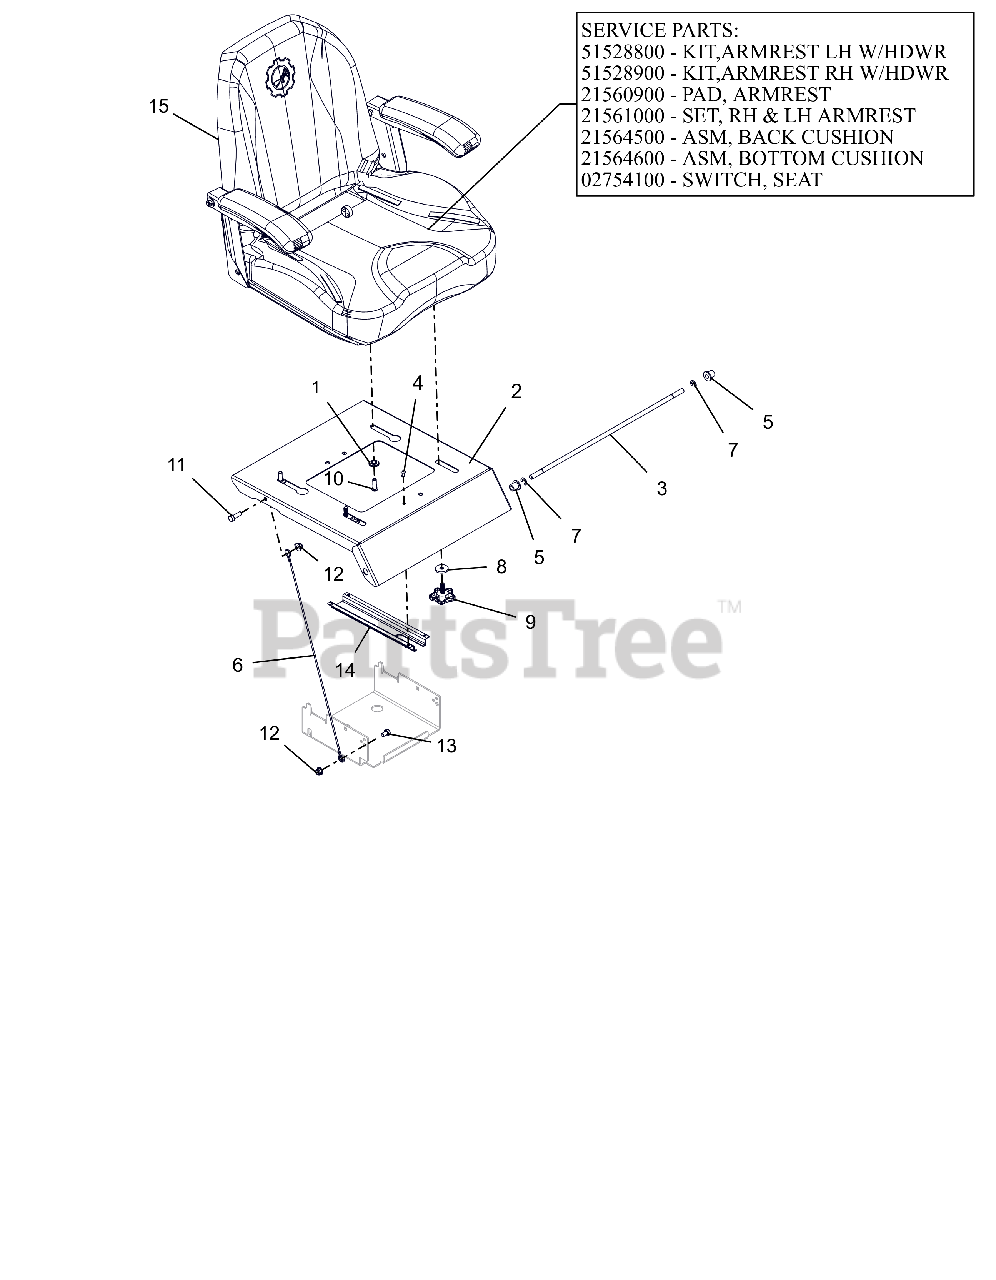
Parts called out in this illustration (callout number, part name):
1	BSHG, FLG .312X.499X.23X.88
2	PLATE, SEAT (FASTENER SLIDE)
3	ROD, SEAT PIVOT
4	RVT-POP.187X.527 DOME ST
5	BSHG-FLG .38X.580X.667X.750
6	LANYARD, SEAT CABLE .093X19.5
7	RG-RTNG-EXT .375X.035 TYP E
8	WSHR, FLT .340X1.125X.135 ZCC
9	KNOB, WING STUDDED
10	BLT,SHCS-BTN .31-18X1.00 ZCC
11	BLT,HEX .31-18X1.00 G5 ZCC
12	NUT,LK-NYL-FLG .31-18 G5ZC120
13	BLT, HEX .31-18X.50 GR5 ZCC
14	GUARD, SEAT SWITCH (GREY PEARL)
15	SEAT, IKON
15	KIT, ARMREST LH
15	KIT, ARMREST RH
15	PAD, ARMREST (HARD)
15	SET,RH & LH ARMREST -HARD
15	ASM, BACK CUSHION-ARIENS X
15	ASM, BOTTOM CUSHION-ARIENS X
15	SWITCH- SNAP MTG N.O.
